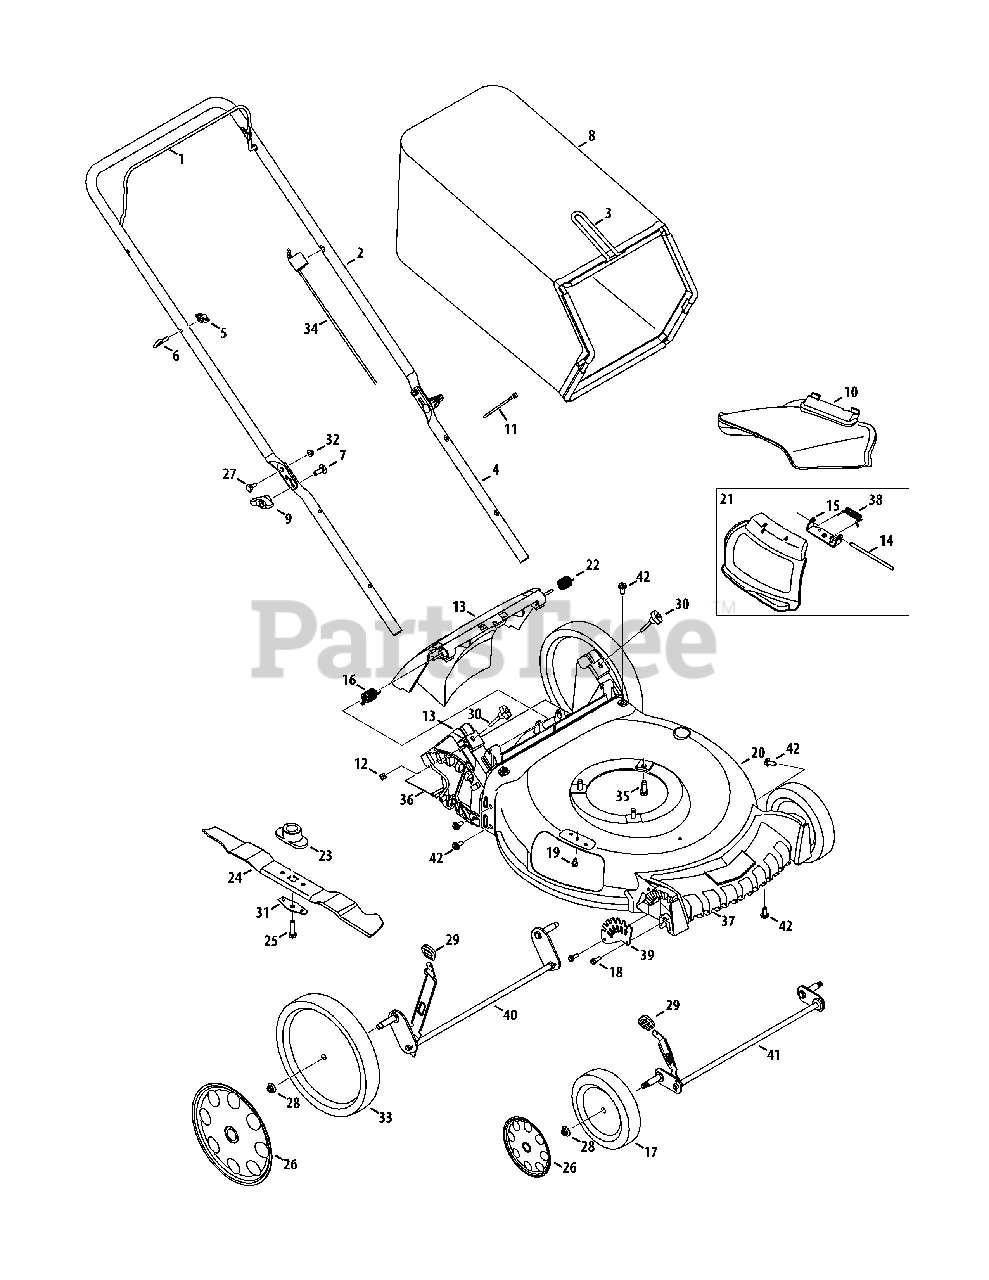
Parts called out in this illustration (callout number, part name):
1	Blade Control
2	Upper Handle
3	Grass Catcher Frame
4	Lower Handle
6	Rope Guide
7	Carriage Screw ,5/16-18
8	Grass Bag
10	Side Chute
10	Side Chute w/Flap
11	Cable Tie
12	Nut, Sq., 1/4-20
13	Rear Discharge Door Assembly
13	Rear Discharge Door Assembly (Lowes 766)
15	Chute Deflector Bracket
16	Torsion Spring - RH
17	Front Wheel
18	Screw, 1/4-15 x .750
19	Screw, 1/4-20 x .500
20	Deck , 21"
21	Hinged Mulch Plug Assembly
22	Torsion Spring - LH
23	Blade Adapter
24	Mulching Blade
25	Screw , 3/8-24 x 1.50
26	Hub Cap - Front
26	Hub Cap - Rear
27	Sldr. Screw, .375 x .126 x 1/4-20
28	Flange Lock Nut, 3/8-16
29	Adjustment Lever Knob
30	Wing Nut
31	Blade Bell Support
32	Nut, Flange Lock, 1/4-20
33	Rear Wheel
34	Control Cable
35	TT Sems Screw, 3/8-16 x 1.0
36	Trail shield
37	Front Cover
38	Torsion Spring
39	Front Height Adjuster Plate
40	Rear Axle Assembly
41	Front Axle Assembly
42	Screw, 5/16-14 x .750
